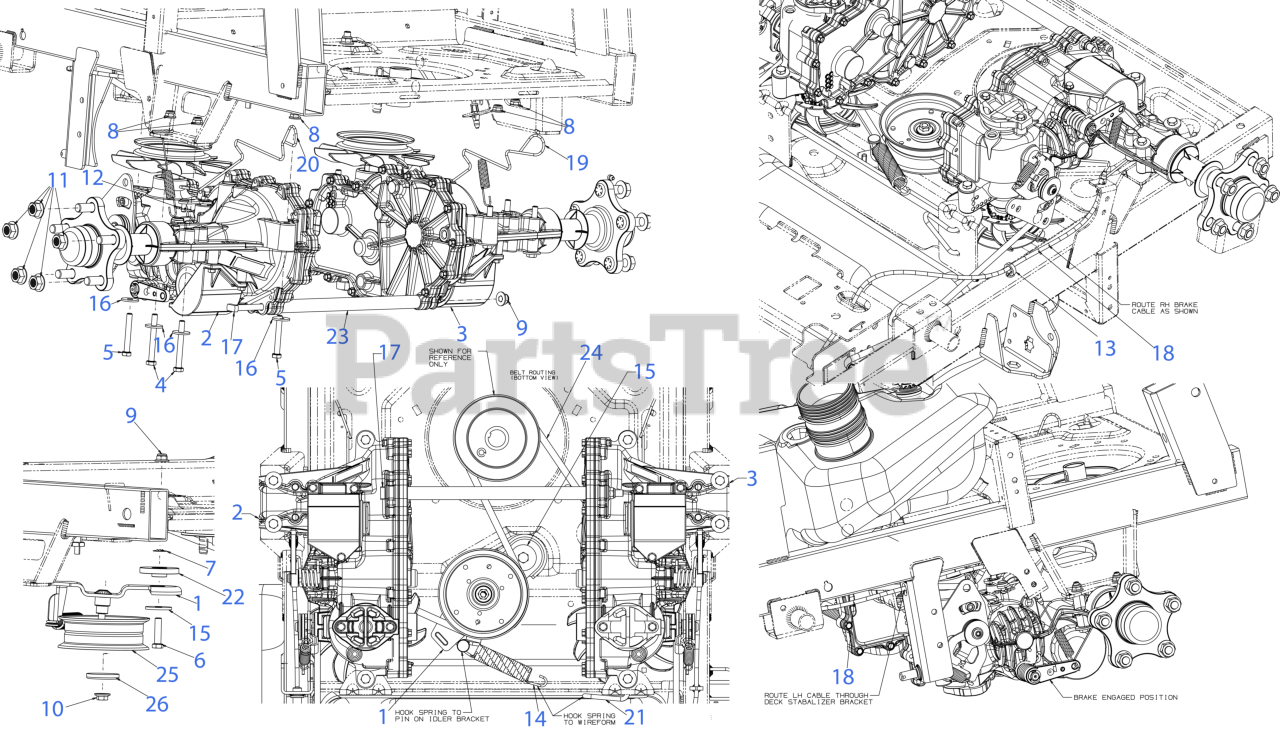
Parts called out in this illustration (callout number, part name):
1	DRIVE IDLER BRACKET
2	HYDRO TRANSMISSION (LH)
3	HYDRO TRANSMISSION (RH)
4	HEX SCREW 5/16-18 x 2.75
5	HEX SCREW 5/16-18 x 2.25 GR5
6	SCREW 3/8-16 x 1.50
8	FLANGE LOCK NUT 5/16-18
10	FLANGE LOCK NUT
11	HEX FLANGE NUT 1/2-20 GR8
12	BOW TIE COTTER PIN 1/4-5/16
13	CABLE RETAINER CLIP
14	EXTENSION SPRING .925 x 5.37
15	FLAT WASHER .390x1.500x.134
16	FLAT WASHER 1.0 OD:.331 ID
17	SUPPORT TUBE ROD
18	PARK BRAKE CABLE
19	HYDRO BYPASS ROD (RH)
20	HYDRO BYPASS ROD (LH)
21	IDLER SPRING HOOK
22	SHOULDER SPACER
23	SUPPORT TUBE
24	TRANSMISSION DRIVE BELT A x 67
24	Cub Cadet TRANS DRIVE BELT A x 67 RZT
24	Troy-Bilt TRANSMISSION DRIVE BELT
25	IDLER PULLEY 4.50" DIA
26	IDLER PULLEY CAP
